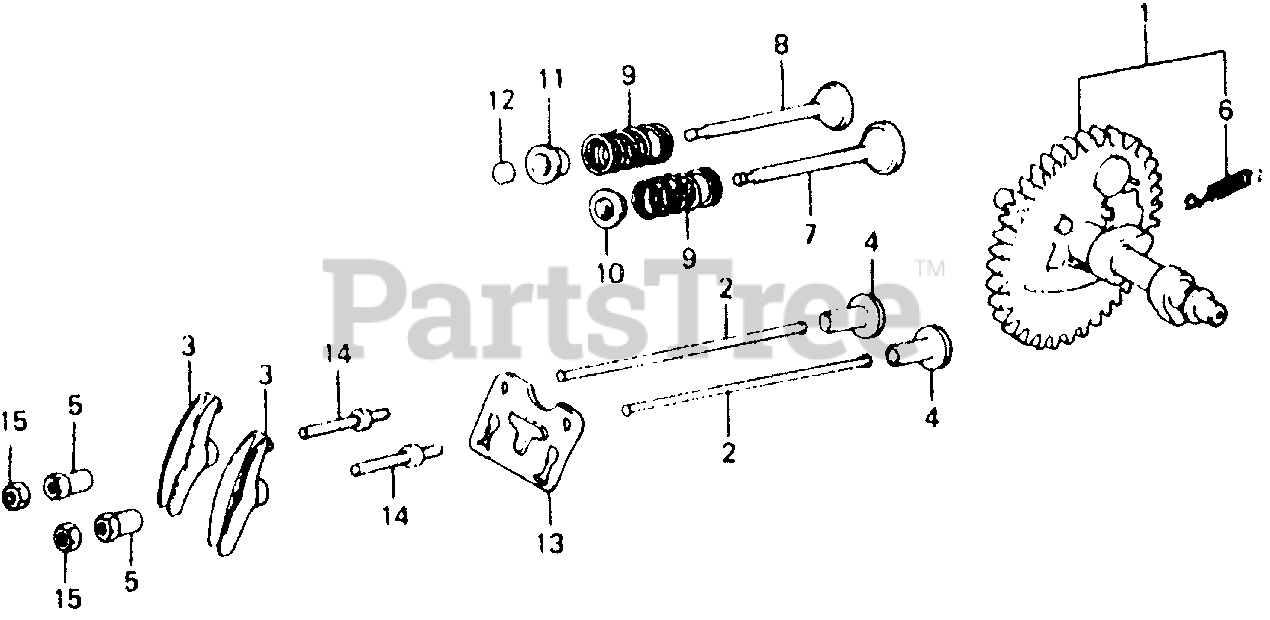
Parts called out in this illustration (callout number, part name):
1	CAMSHAFT ASSY.
2	ROD, PUSH
3	ARM, VALVE ROCKER
4	LIFTER, VALVE
5	PIVOT, ROCKER ARM
6	SPRING, WEIGHT RETURN
7	VALVE, IN.
8	VALVE, EX.
8	VALVE, EX. (STELITE)
9	SPRING, VALVE
10	RETAINER, IN. VALVE SPRING
11	RETAINER, EX. VALVE SPRING
12	ROTATOR, VALVE
13	PLATE, PUSH ROD GUIDE
14	BOLT, PIVOT (8MM)
15	NUT, PIVOT ADJ.
